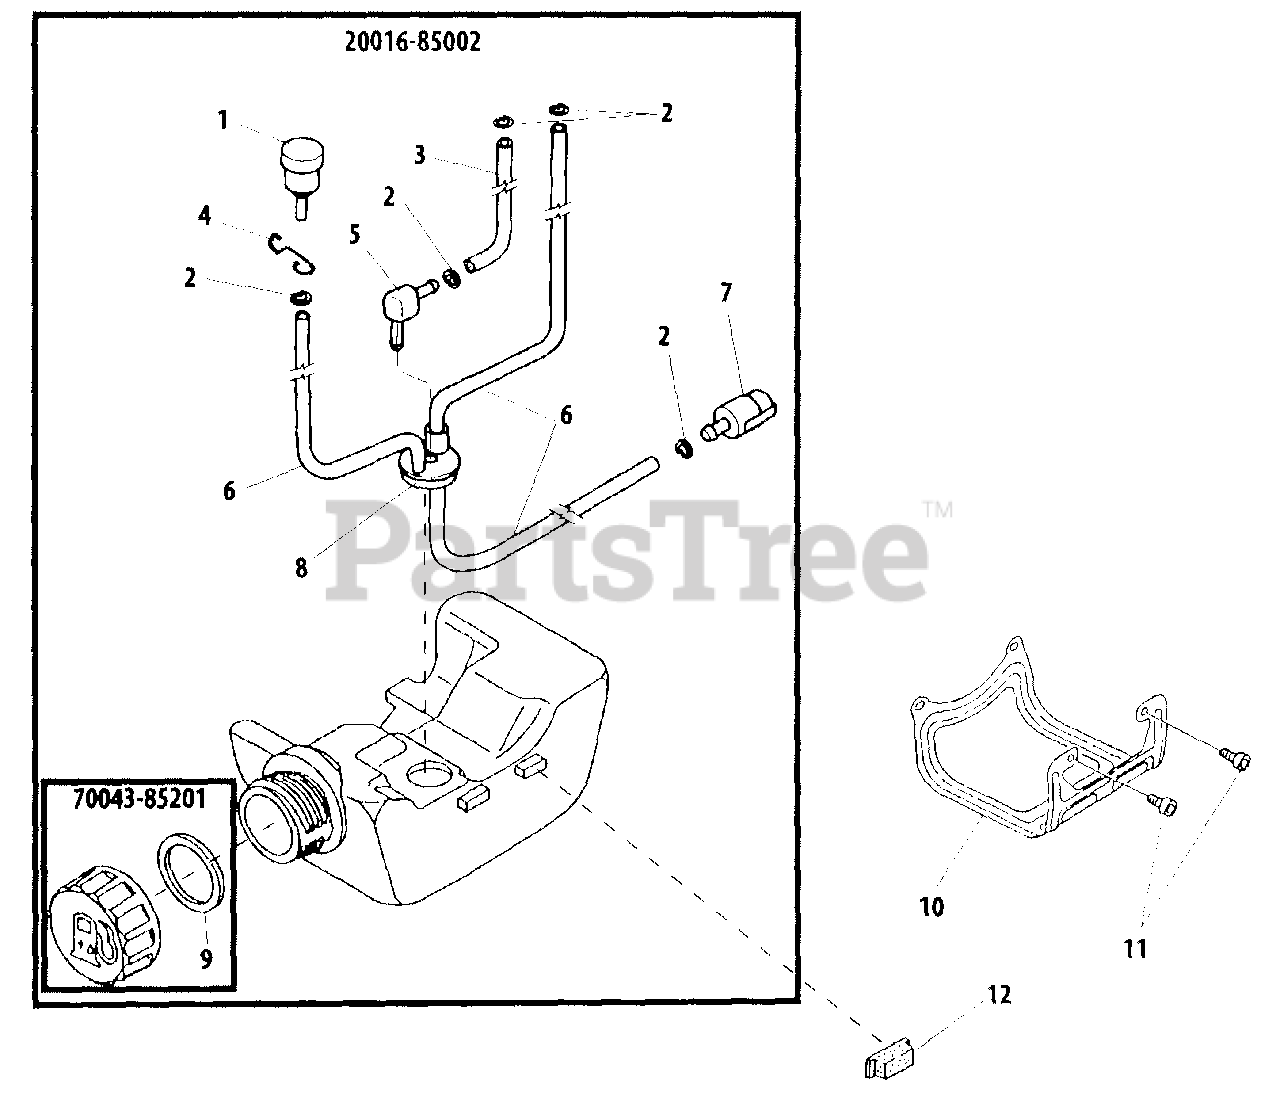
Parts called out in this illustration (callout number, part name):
1	VENT ASSY
2	CLIP Ø6
3	PIPE, RETURN
4	CLIP, VENT ASSY
5	CONNECTOR, PIPE
6	PIPE, FUEL
7	FILTER, FUEL 125-528
8	GROMMET
9	GASKET, FUEL CAP
10	GUARD, METAL FUEL TANK
11	BOLT M5×12
12	CUSHION, FUEL TANK
20016-85002	FUEL TANK ASSY
70043-85201	CAP ASSY, FUEL
